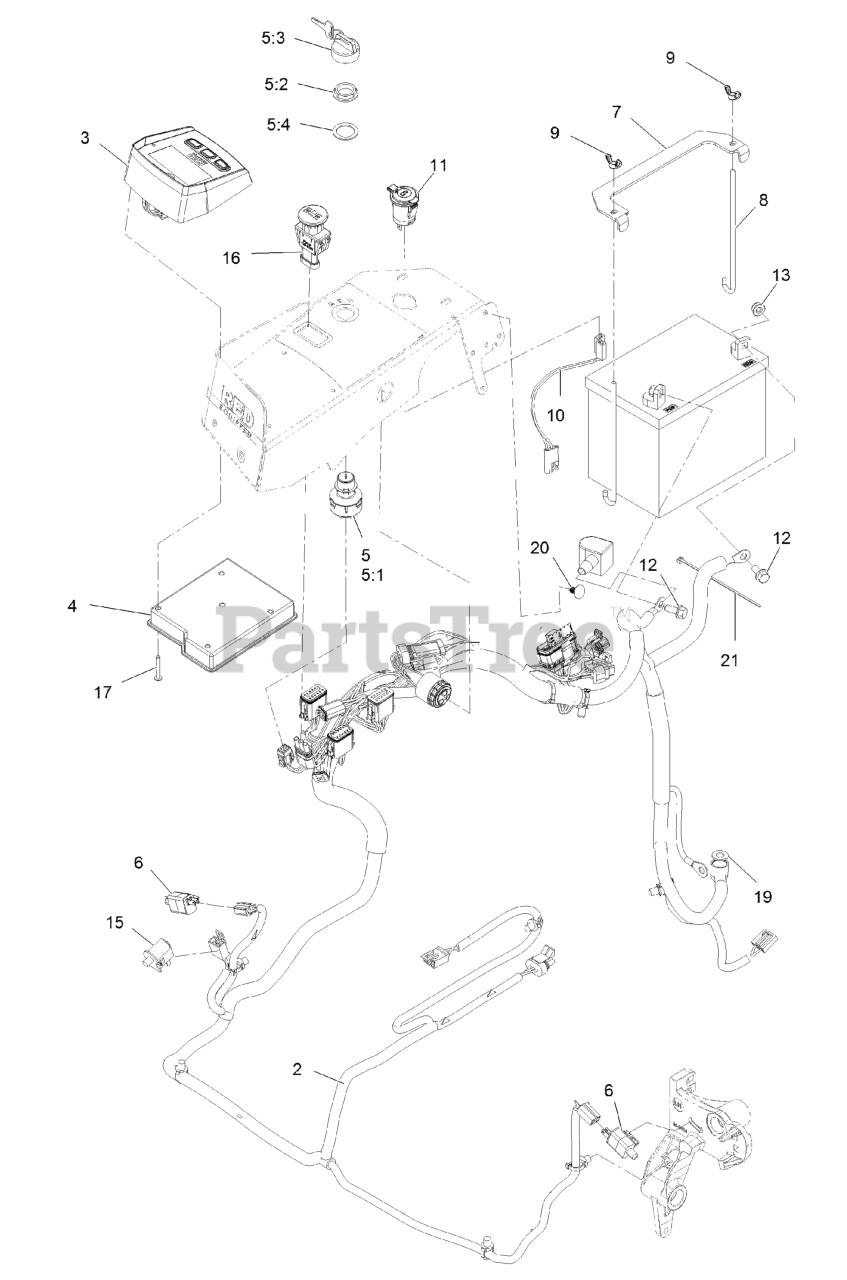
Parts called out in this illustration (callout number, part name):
2	HARNESS-WIRE
3	MODULE, LDU
4	Module-Mcu
5	IGNITION SWITCH ASM
5:1	Switch-Ignition
5:2	NUT-MOUNTING
5:3	IGNITION KEY SET
5:4	WASHER-BACKUP
7	STRAP-TIE DOWN, BATTERY
8	BOLT-HOLDDOWN
9	WINGNUT
10	HARNESS-RECEPTACLE, 12V
11	PORT-POWER, 12V
12	SCREW-HHF
13	NUT-HF, NI
15	SWITCH-BAIL
16	SWITCH-PTO, SEALED
17	SCREW-PPH
19	WASHER-FLAT
20	PLUG-PLASTIC
21	TIE-CABLE
